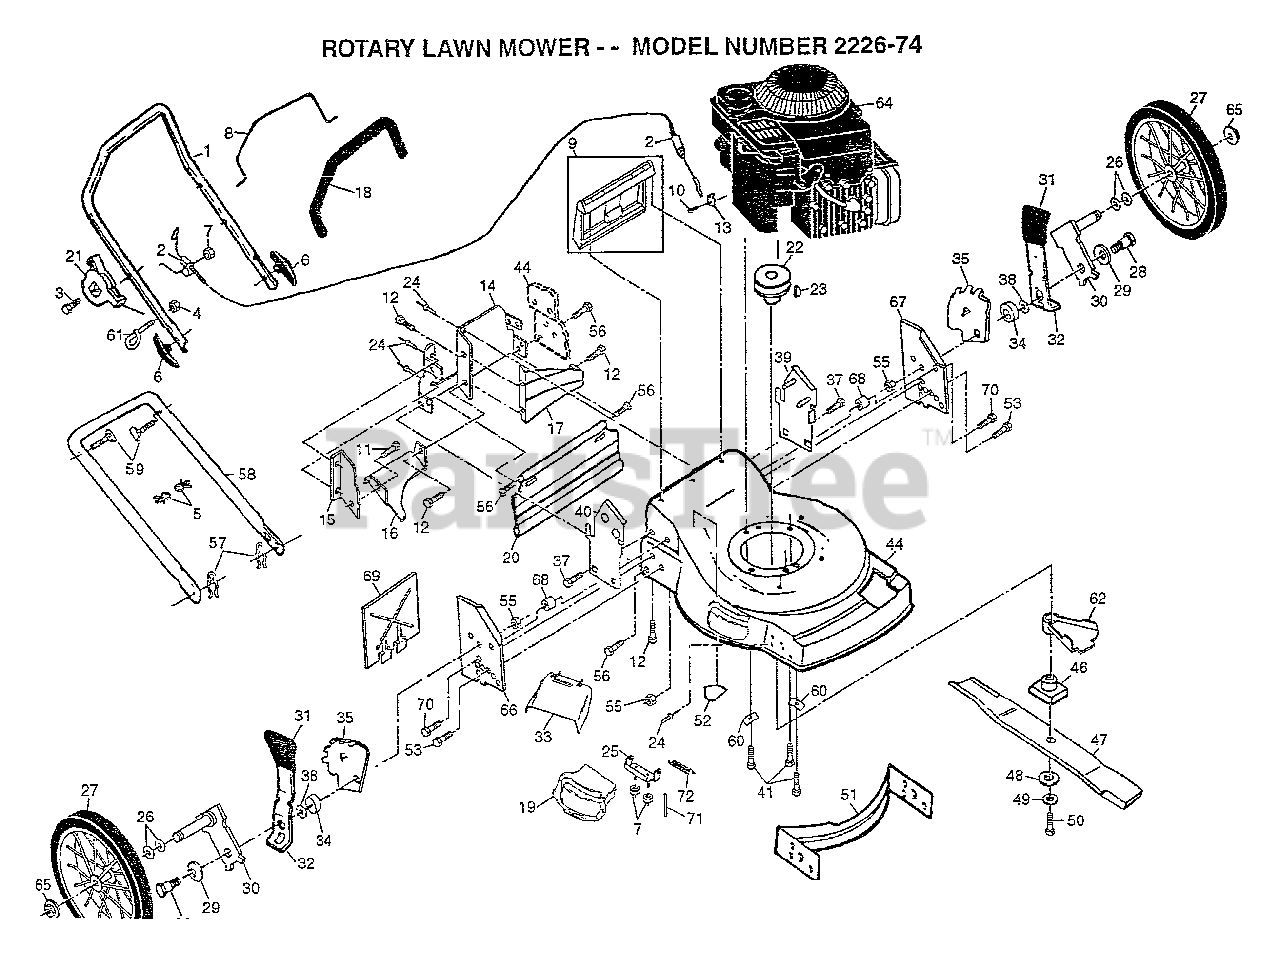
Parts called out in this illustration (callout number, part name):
1	HANDLE.UP.DLX.CON SUBS/1
2	"CABLE,ENG ZONE CO"
3	SCREW.HXHD.WASH.
6	KNOB HANDLE
8	BAIL.CNTRL.DLX.
9	KIT.DOOR.RR.22.PL
10	SCREW PM
11	SCREW.HXTAP.10-24
12	SCREW
13	CABLE CLAMP
14	PLATE.BACK
16	DISCHARGE BAFFLE
17	REAR BAFFLE
19	DOOR.MULCH.COMBI
20	SKIRT.REAR.FGD.22
21	"CONTROL, THROTTLE"
22	ENGINE.PULLEY.FWG
23	HI PRO KEY PM
24	BLIND RIVET
25	BRACKET.HINGE.W/F
26	WAVE WASHER
27	ASM WHL & TIRE
28	BOLT SHLD 3/8-16
30	AXLE ARM ASSY R
31	KNOB PM
32	SPRING SELECTOR
33	GUARD.DISCH.CLIPO
34	SPACER.HEIGHT.ADJ
35	BRACKET.ADJ.9POS.
37	SCREW.HXWS.5/16
38	WASHER PM
39	BRKT.ASM.HDL.LH
40	BRACKET.ASM.HD.RH
41	BOLT.ENG.3/8-16
44	HOUSING ASSEMBLY
46	ADAPTOR.BLADE.LM
47	"BLADE.MULCH.22"""
48	"WASHER,HARDEN"
49	LOCKWASHER
50	SCREW
51	KIT.BAF.FRT.22RD
52	DECAL HYT
55	LOCKNUT PM
56	HINGE SCREW
57	HAIRPIN COTTER
58	LOWER HANDLE
59	BOLT.HANDLE.LM
61	ROPE GUIDE
65	HEX FLANGE LOCKNT
66	WHL.BRKT.SUPT. RH
67	WHL BRKT SUPT LH
69	MULCHER PLATE
70	SCREW.HX.WSHD.
71	ROD.HINGE.COMBI-C
72	SPRING.HINGE
